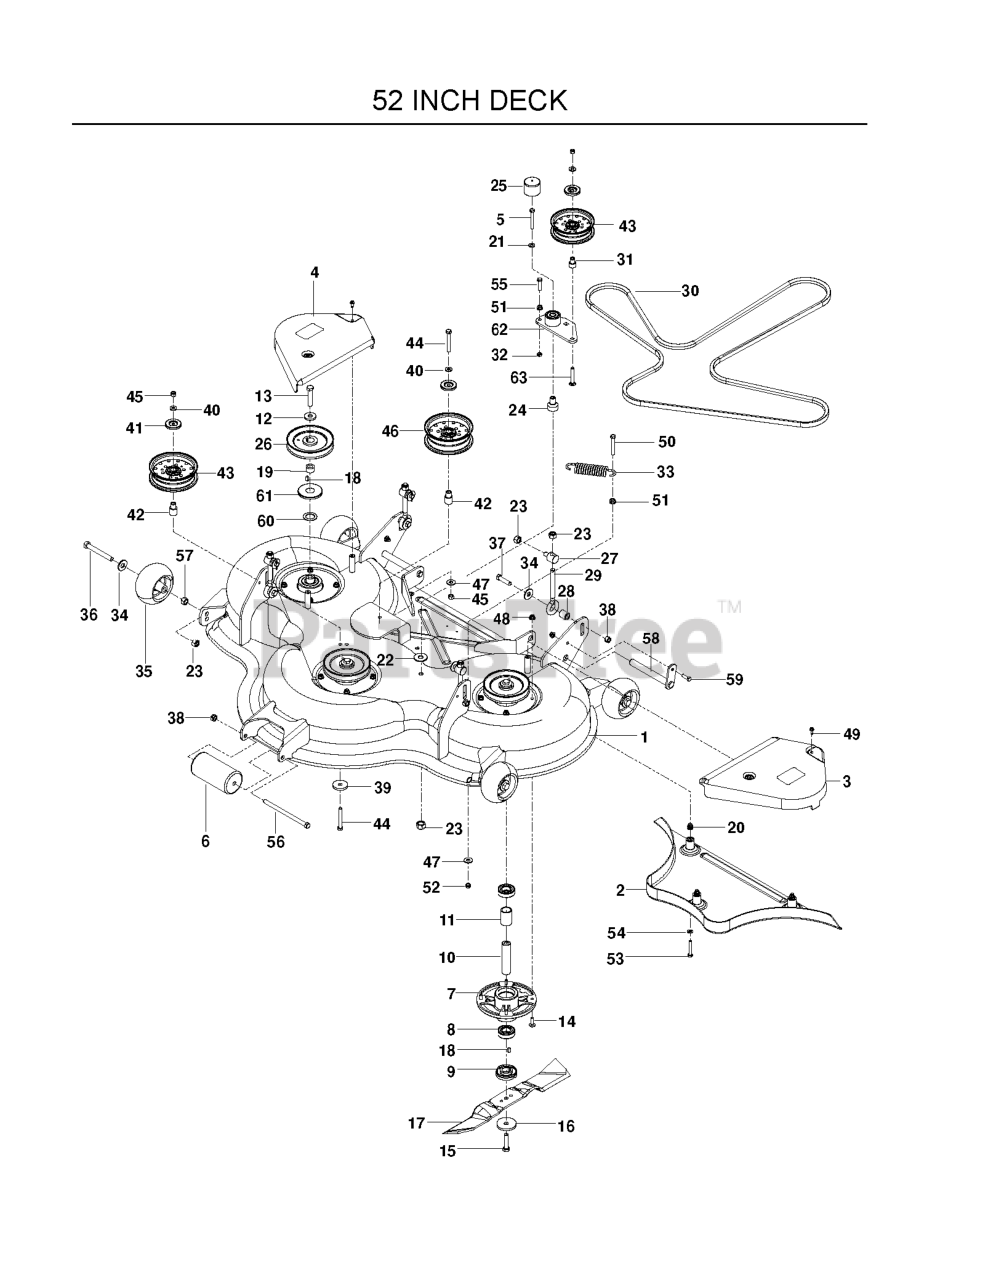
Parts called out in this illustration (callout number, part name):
1	DECK W/DECALS, 52L HUS
3	BELT SHIELD LT
4	BELT SHIELD RT
5	SCREW, 1/2C X 3 HEX CAP
6	ROLLER
7	BEARING HOUSING
8	BALL BEARING
9	BUSHING, BLADE
12	WASHER-.533IDX1.37OD
13	HCS M12 X 1.75 X 60 GR5 ZD
14	RHSNB 5/16C X 1
15	HCS M12 X 1.75 X 50 GR8.8 ZD
17	BLADE REAR DISCHARGE/MULCH C13
19	KEY RETAINER
20	BLIND RIVET NUT
21	CONTACT BELLSPR 1/2
22	WASHER, SUPPORT
23	NUT 1/2-13 HEX NYLOC ZD
24	PIVOT, BEARING
25	CAP, VINYL
26	PULLEY, 52
30	BELT, DECK 52 COMBI/60 GRIZZY
31	BUSHING, IDLER
32	NUT 3/8-16 HEX JAM
34	WASH USS FLAT 1/2
35	GAUGE WHEEL
36	HCS 1/2-13 X 4 GR 5 ZD
37	HCS 7/16 - 14 X 1 3/4
38	NUT 7/16C CENTERLOCK
39	SPINDLE WASHER
40	WASHER, 3/8 THICK
41	DUST SHIELD
42	IDLER BUSHING
43	IDLER PULLEY
44	SCREW 3/8C X 2 3/4 HEX CAP
45	NUT 3/8-16 NYLOC
46	IDLER PULLEY (TALL)
47	WASHER 3/8 FLAT
48	5/16-18 NYLOC FLANGE NUT
49	SCREW 1/4 X 5/8
50	HCS 3/8C X 2
51	NUT 3/8C WHIZ
52	NUT HEX 3/8-16 NYLON, THIN
53	HCS M8 X 1.25 X 50 GR8.8 ZD
54	FLAT WASHER 5/16 SAE
55	HCS 3/8-16 X 1-1/2
56	HCS 7/16-14 X 7 GR5 ZD
57	NUT HEX 1/2
58	PIN, STRUT, WELDMENT
59	HCS 5/16C X 1
60	WASHER-1.06IDX1.63ODX.06
61	BOTTOM DUST CAP
62	ARM-IDLER W/BRG
63	CARRIAGE BOLT 3/8-16 X
